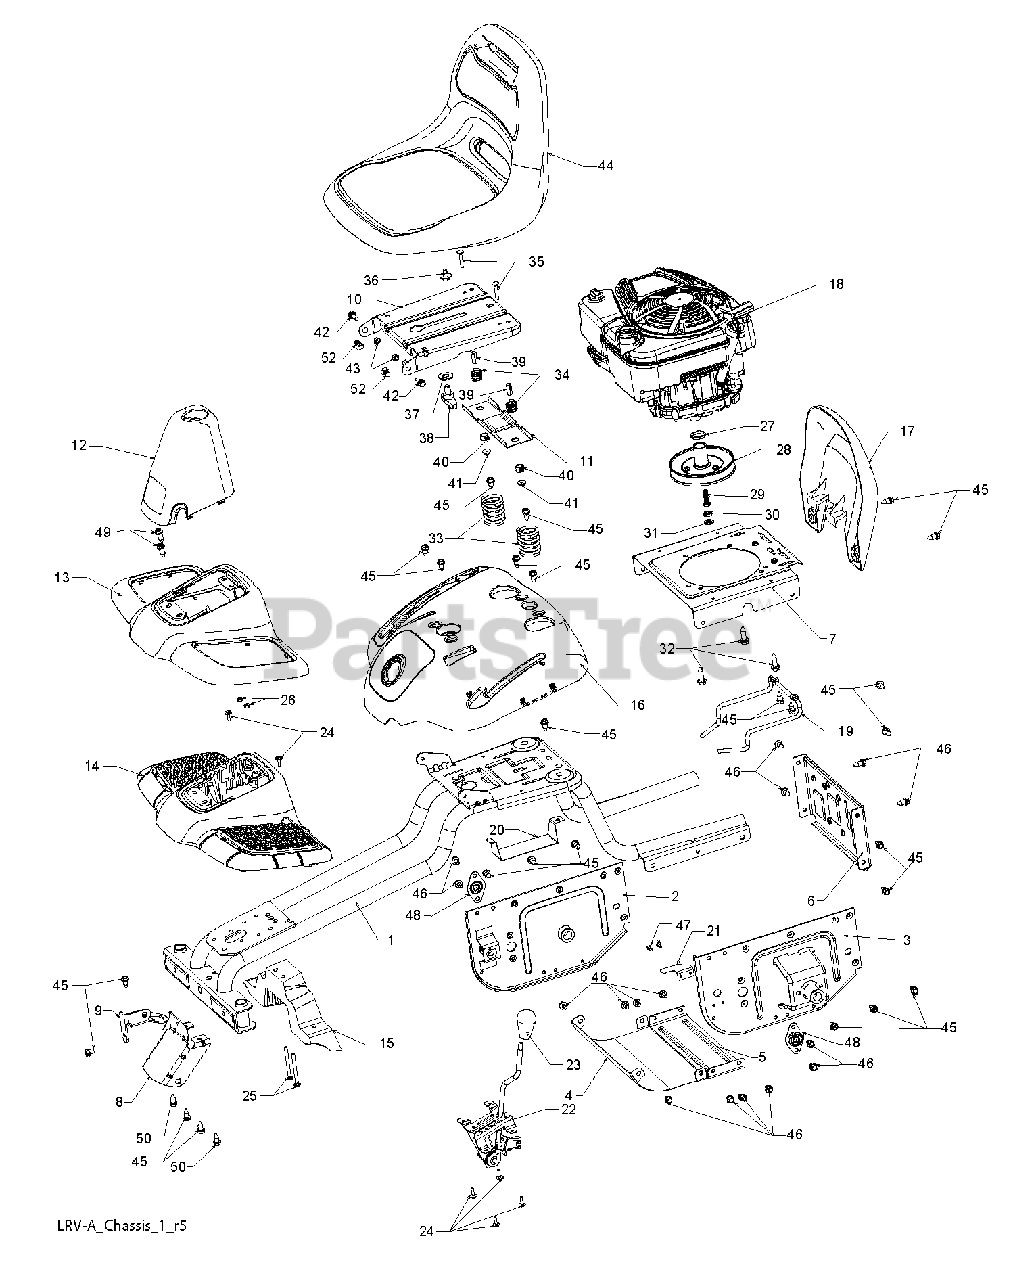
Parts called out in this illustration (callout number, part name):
1	CHASSIS.WLD.26".LRV
2	SUPPORT, AXEL LH
3	RP SUPPORT, AXLE RH
4	SHIELD, TRANSAXLE FRONT
5	STRAP.CROSS.FRICTION.DRIVE
6	COVER, FRICTION DRIVE
7	PLATE, ENGINE
8	BRACKET, CHASSIS FRONT
9	BRACKET, STEERING SUPPORT
10	PAN.ASM.SEAT.1SLOT
11	BRKT.MNTNG.SWITCH.SEAT.BLACK
12	BOOT, DUST LRV (2 2)
13	FOOTREST.AESTHETIC.WE.GRN.LRV
14	STRUCTURE, FOOT REST
15	SUPPORT, FOOT REST
16	FENDER.CNTRL.PNL.WE.GRN.LRV
17	GUARD.ENGINE.LRV
19	KEEPER, BELT
20	BRACKET, BATTERY LRV
21	LEVER, SWITCH
22	CABLE.ASM.CLUTCH.W/BRACKET
23	KNOB.OVAL.CUSTOM.BLACK
24	SCREW.#10 X 0.750.BOS (2 2)
25	BOLT.CARRIAGE
26	NUT
27	SPACER.ENGINE.B&S.LRVA
28	DISC, FRICTION ASM
29	BOLT, SCKT HD 3/8-24 X 1 .25
30	BEARING.BALL.689ZZ
31	SPACER.NEUTRAL
33	SPRING COMPRESSION
35	BOLT.ROUND.HEAD.SQUARE.NECK
36	BOLT,SHOULD
38	KNOB.SEAT.ADJ.WINGNUT
39	SPACER SPLIT 28X.96
41	NUT T
42	BOLT.SHOULDER.5/16-18
43	NUT.71038.31-18.HEX.NYLOCK
44	SEAT.SUBASY.OPP.WEEDEATER.LRVA
45	SCREW
46	SCREW LT
48	BEARING FLANGE BALL
49	SCREW 5/16-18X1
50	BOLT.SHOULDER.5/16-18X
52	PUSH CLIP
